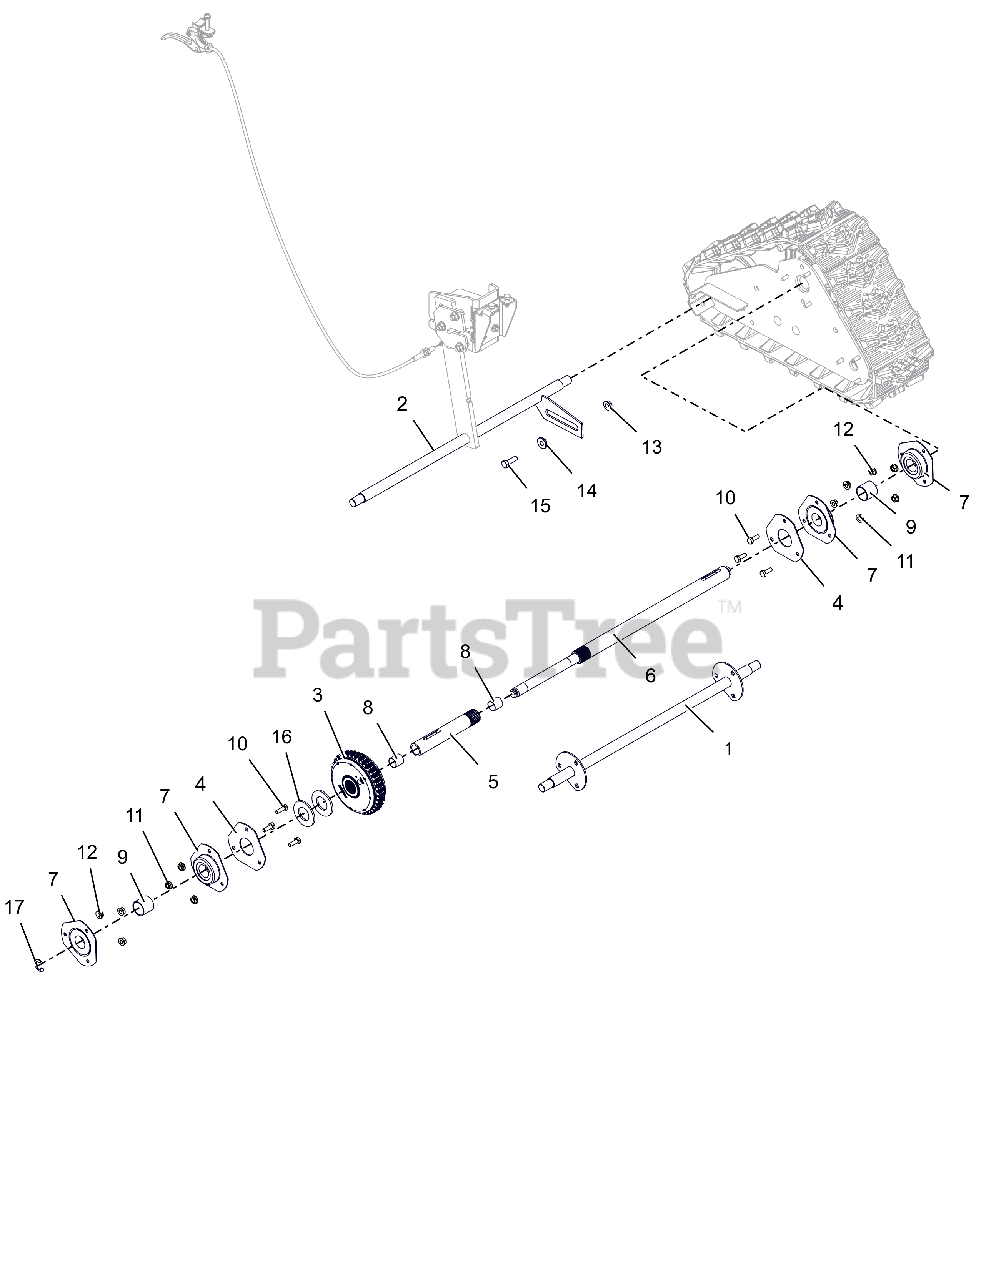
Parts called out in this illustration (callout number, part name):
1	AXLE, FRONT - PRO
2	AXLE, REAR - PRO TRACK
3	DIFFERENTIAL, AUTOMATIC
4	PLATE, BEARING SPACER
5	AXLE, SHORT-W/BUSHINGS
6	AXLE, LONG-TRACK DIFFERENTIAL
7	BRG-FLG 1.003/1.000 3 BOLT
8	BSHG-SLV .706X.764X.75 BRZ
9	BSHG-SLV, 1.012X1.125X1.00
10	@BLT-HEX .25-20X.75 GR5 YWZC
11	@NUT-LK-CTR-FLG .25-20 YWZC
12	@NUT-LK-TOP-FLG .25-20 YWZC
13	@NUT-LK-TOP-FLG .31-18 YWZC
14	BSHG-FLG .325X.499X.3X.875
15	@BLT-HEX .31-18X1.00 GR5 YWZC
16	WSHR-FL-STL- 1.062X2.0X.134 YZ
17	RG-RTNG-EXT .625X.042
